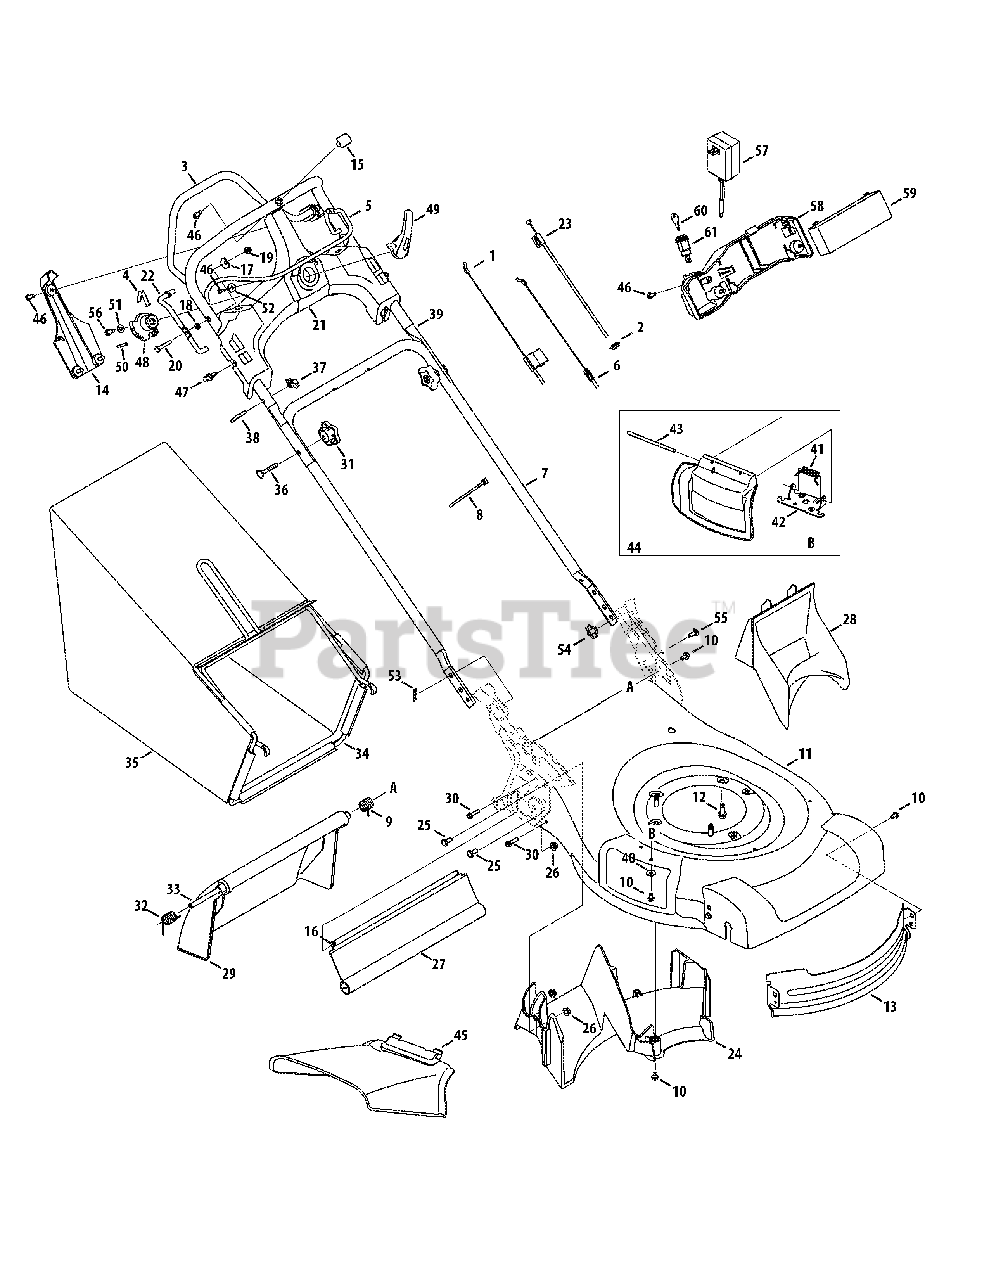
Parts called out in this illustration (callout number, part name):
1	Drive Cable
2	Rubber Grommet
5	Blade Control
6	Control Cable
8	Cable Tie
9	Torsion Spring, LH
10	TT Screw, 1/4-20 x .500
13	Front Deck Bae
14	Variable Speed Cont. Panel Cover
15	Variable Speed Cont. Panel Cover
16	Screw, #10-16 x .500
17	Saddle Washer
18	Washer, Lock, 1/4
19	Nut, Flange Lock, 1/4-20
20	Screw, 1/4-20 x 1.50
21	Variable Speed Control Panel
22	Bail Pivot Rod - RH
22	Bail Pivot Rod - LH
23	Variable Speed Cable
25	Screw, 5/16-18 x .625
26	Flange Lock Nut, 5/16-18
27	Trailshield
28	Mulch Plug
29	Rear Door
30	Screw, 1/4-15 x 1.00
31	Star Knob
32	Torsion Spring, RH
33	Door Pivot Rod
36	Carriage Bolt, 5/16-18 x 2.00
40	Bell Washer, .265 x .75 x .062
41	Torsion Spring
42	Chute Deector Adapter
43	Hinge Pin
44	Mulch Plug Assembly
45	Side Discharge Chute
46	Screw, #12-16 x .75
47	Rivet, Plastic
48	4 Speed Actuator
49	Speed Selector Level
51	Washer, Flat, .344 x .688 x .065
52	Washer, Flat, .250 x .750 x .119
53	Cotter Pin
54	Wing Nut
55	Carriage Bolt, 1/4-20
56	Screw, 1/4-15 x .750
57	Battery Charger
58	Harness Assembly
59	Battery, 12V
60	Ignition Key
61	Key Switch
